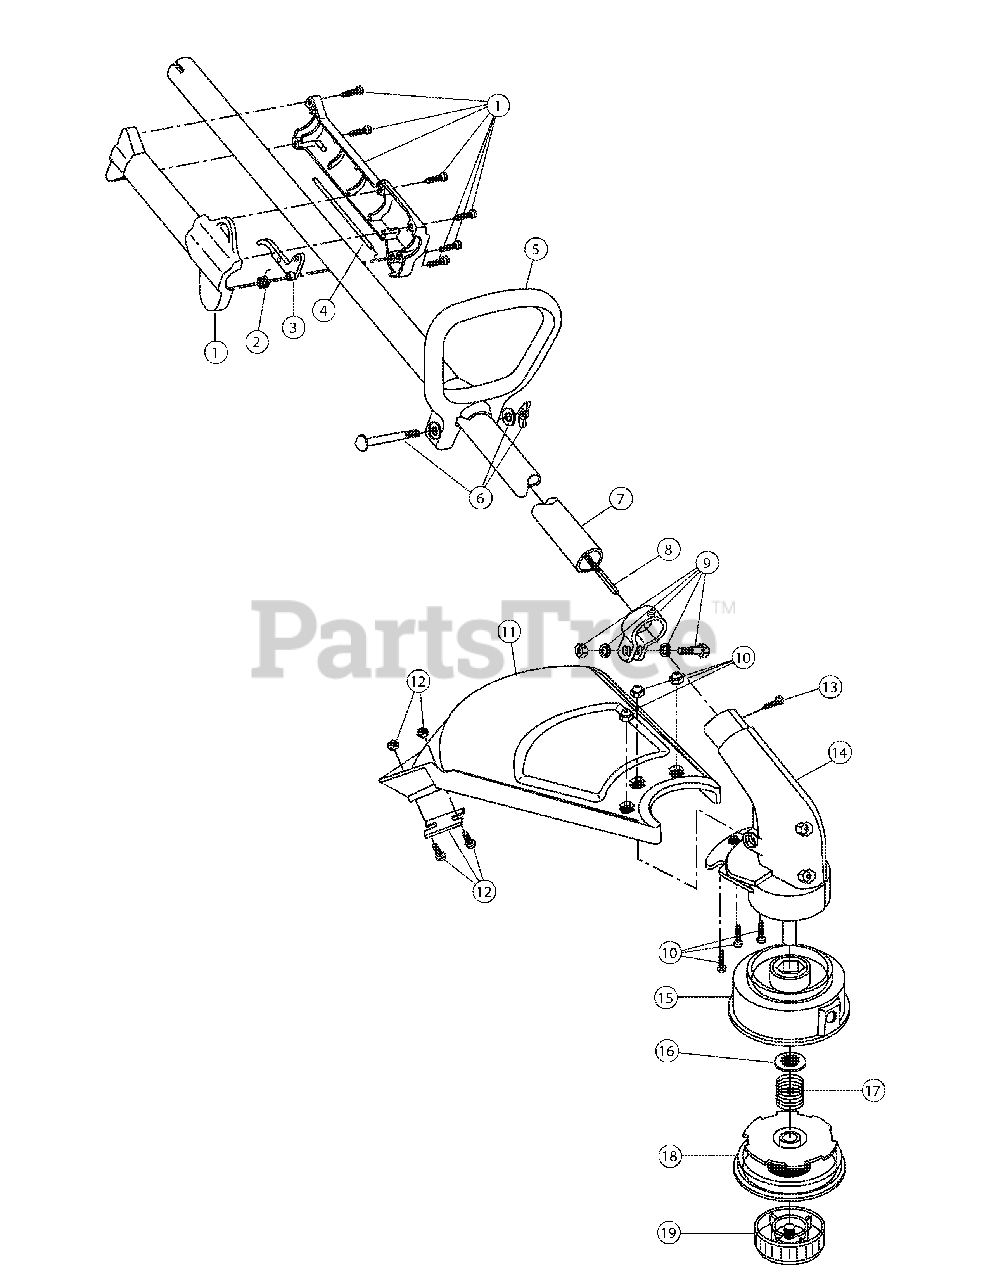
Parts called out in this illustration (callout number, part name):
1	Throttle Housing Assembly
2	Throttle Trigger Spring
3	Throttle Trigger
4	Throttle Cable
5	D-Handle Assembly
6	D-Handle Hardware
7	Drive Shaft Housing
8	Flexible Drive Shaft
9	Lower Clamp Assembly
10	Guard Mounting Hardware
11	Guard Assembly
12	Blade Assembly
13	Anti-Rotation Screw
14	Gearbox Assembly
15	Outer Spool Assembly
16	Retainer
18	Inner Reel
19	Bump Head Knob Assembly
